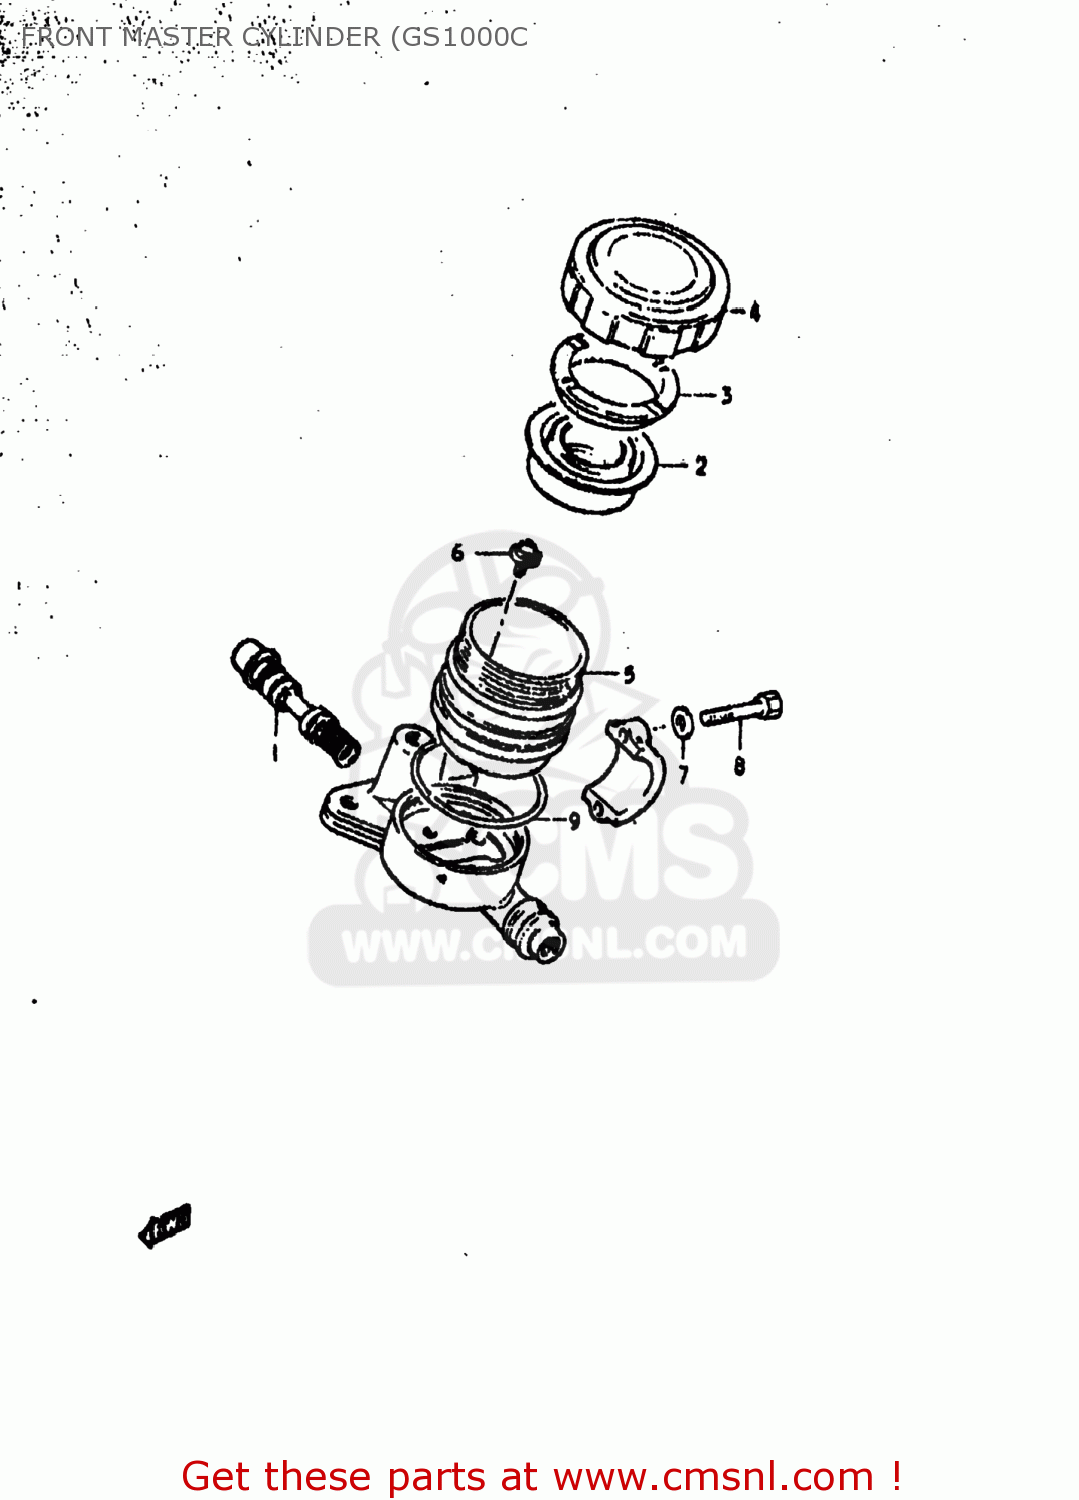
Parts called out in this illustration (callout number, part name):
1	PISTON & CUP SET
2	DIAPHRAGM
3	PLATE
4	CAP,MASTER CYLINDER,REAR
5	RESERVOIR
6	SCREW,MASTER CYLINDER
7	WASHER
8	BOLT
9	O RING
